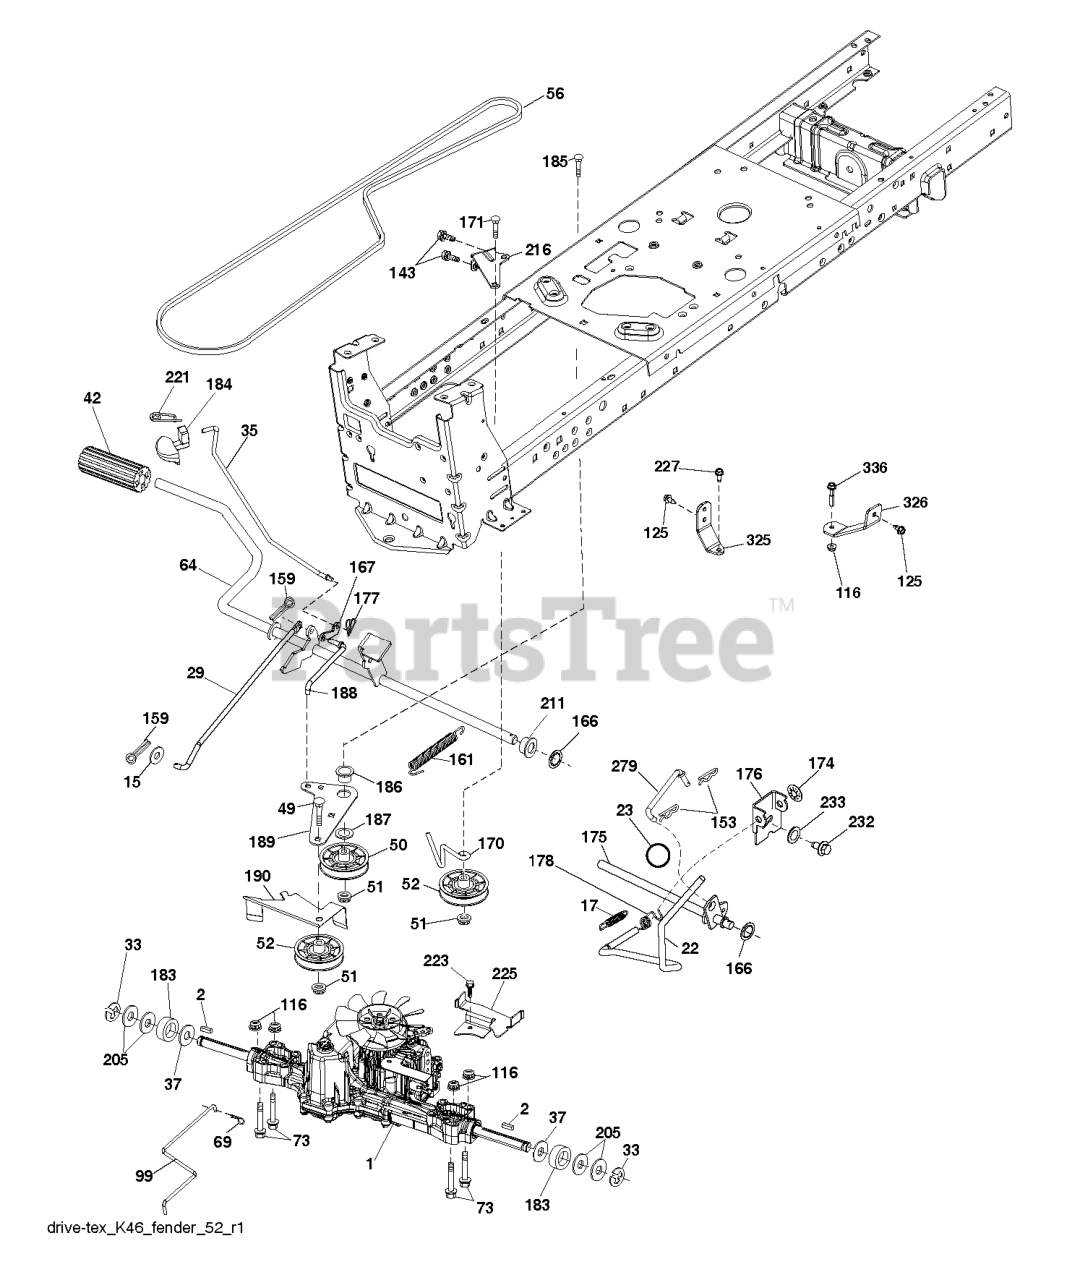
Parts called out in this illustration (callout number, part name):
2	SQUARE KEY
15	WASHER
17	SPRING.BRAKE.K46.GREEN
22	ROD.SHIFT.FENDER.TLT.2006
23	KNOB.DELUXE.(PISTOL.GRIP).BLAC
29	ROD.BRAKE.K46
35	ROD.PRKNGBRK.LT.HUSQ/PRED.PLT
37	WASHER.HARDENED
42	PEDAL COVER
50	IDLER.FLAT.910.OFFSET
51	NUT LOCK FLG 3/8-16 UNC
52	IDLER.V-GROOVE.910.OFFSET
64	SHAFT.ASM.PEDAL.BRAKE.
69	HAIRPIN.SOFT.ZINC.059X1.125
99	ARM.PIVOTING.TCRD.GEN2.5.BAGGE
125	SCREW
153	RETAINER M
161	SPRING, RETURN LT
166	NUT.PUSH.625
167	LATCH.BRAKE.SPRING
170	KEEPER.V-IDLER.CENTER.
174	NUT.PUSH.500.2006
175	SHAFT ASM SHIFT
176	ARM.CLEVIS.ROD.SHIFT
177	PIN COTTER;LOCKING;BOWTIE;1IN
178	SPRING.SHIFT.GT2006
183	SPACER AXLE
184	HANDLE.PARKNG BRK.PRED.LT.428
186	SPACER.RETAINER
188	LINK.CLUTCH.GROUND DRIVE.LONG
189	BELLCRANK.GROUND.DRIVE.TEX.
190	KEEPER.BELLCRANK.DRIVE
211	BUSHING.SHAFT.BRAKE.HAND
216	BRACKET.PULLEY.IDLER.W/TEX
221	RETAINER.SPRING.CLIP.H
225	KEEPER.BELT.TRANSAXLE.K46
279	LINK.SHIFT.T/A.K46.FEND.TX
325	BRACKET.TRQ.STP.46.20".TIRE.LH
326	BRCKT.PNT.TRQ.STP.46.20TIRE.RH
